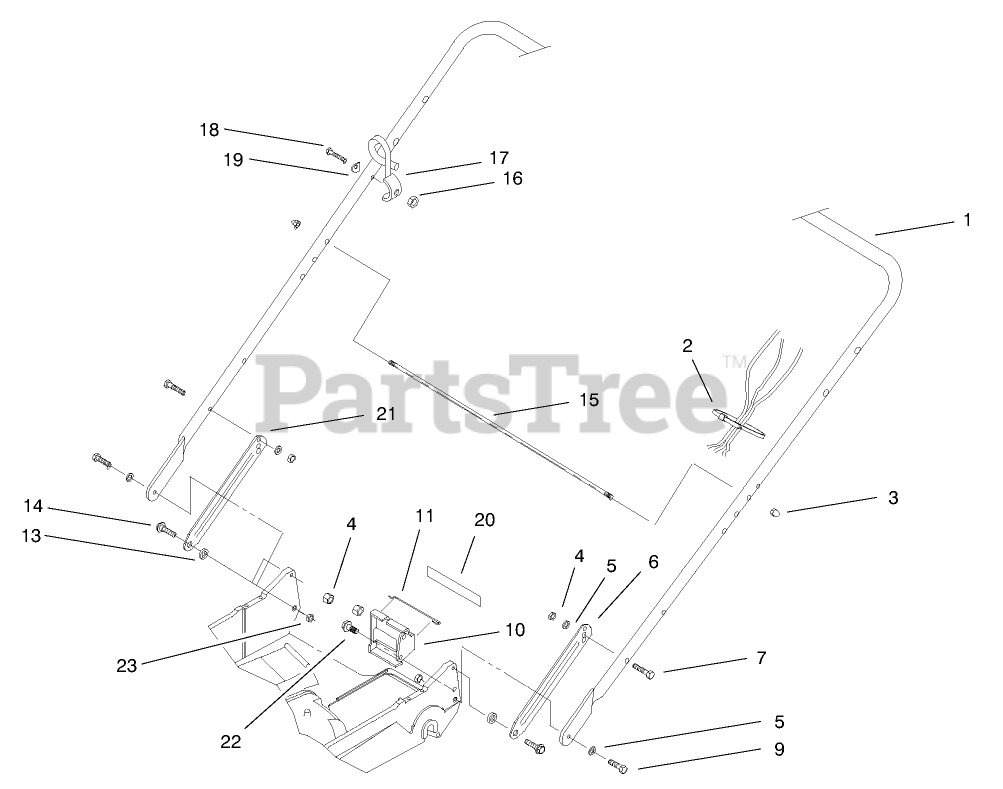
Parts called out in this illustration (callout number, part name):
2	TIE-CABLE
3	NUT-CAP
4	NUT-LOCK, NI
5	WASHER-BELLEVILLE
6	LATCH-HANDLE, LH
7	SCREW-HH
9	SCREW-HH
11	RETAINER-CABLE
13	SPACER
14	SCREW-SHOULDER
15	ROD-SUPPORT, BAG
16	NUT-LOCK, NI
17	GUIDE-ROPE
18	SCREW-HH
19	WASHER
20	DECAL-POSITION, GEAR
21	LATCH-HANDLE, RH
22	SCREW-HWHTF
23	NUT-LOCK, NI
